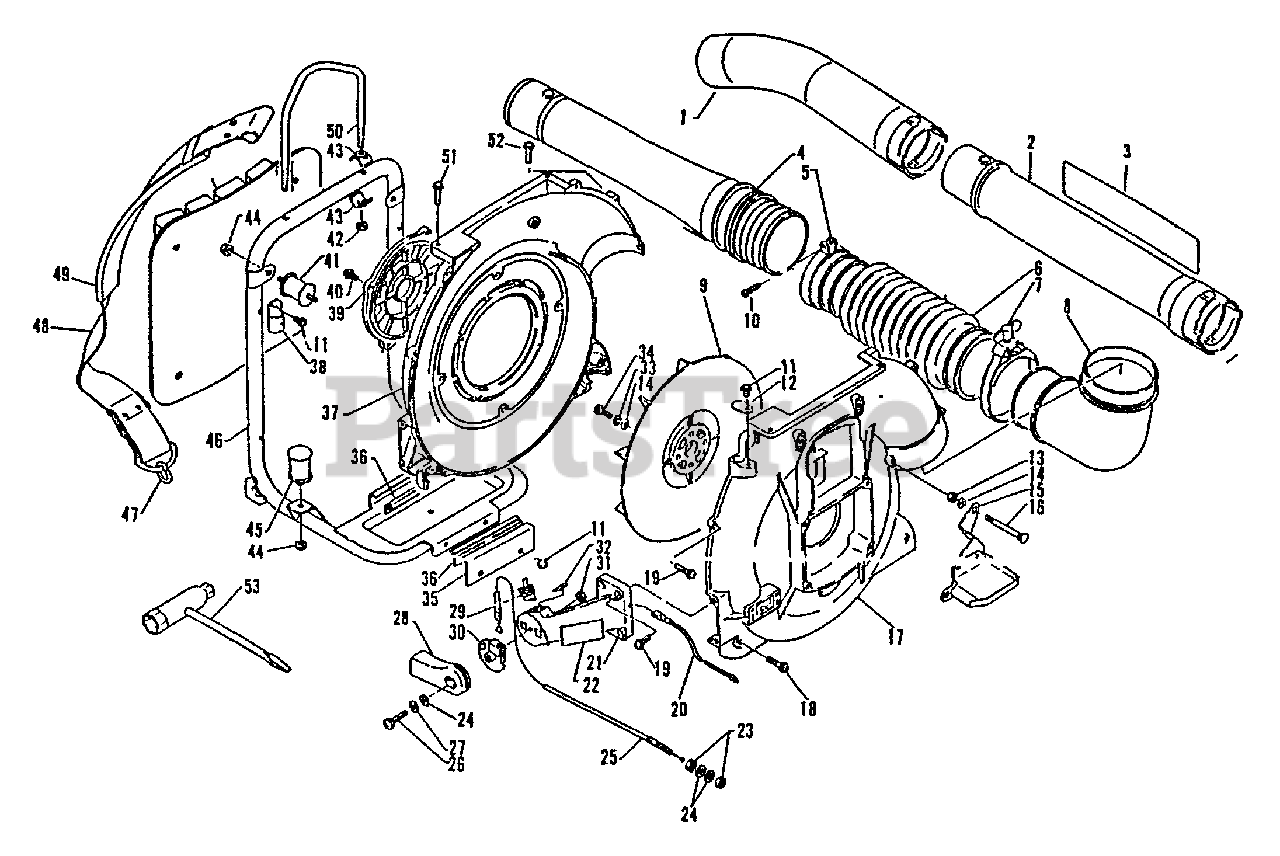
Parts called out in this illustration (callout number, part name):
1	TUBE, BLOWER - CURVED
2	TUBE, BLOWER - STRAIGHT
3	LABEL - LESCO
4	TUBE, BLOWER - SWIVEL
5	CLAMP KIT
6	TUBE, BLOWER - FLEXIBLE
7	CLAMP
8	TUBE, BLOWER - ELBOW
10	SCREW - 5X25
11	SCREW - 5X10
13	NUT - 5
14	WASHER - 5
15	BRACKET, MUFFLER COVER
16	BOLT, ELBOW
17	COVER, FAN - LEFT
18	SCREW - 5X25
19	SCREW - 5X20
21	MOUNT, THROTTLE LEVER
22	LABEL - CAUTION
24	WASHER - 6
25	CABLE, THROTTLE
26	SCREW - 6X25
27	WASHER - 6
28	TRIGGER, THROTTLE
29	IGNITION SWITCH ASSY
31	LOCKNUT - 6
32	LABEL - STOP
33	LOCKWASHER - 5
34	BOLT - 5X16
35	BRACKET, FUEL TANK
36	CUSHION, FUEL TANK
37	COVER, FAN - INNER
38	BRACKET, CUSHION
39	GUARD, DEBRIS
40	BOLT - 6X14
42	LOCKNUT - 6
44	NUT - 6 -- FLANGE
46	FRAME, BACKPACK
47	RING, STRAP
48	BACKPACK STRAP ASSY
49	CUSHION, BACKPACK
51	SCREW - 6X15
52	SCREW - 6X20
53	T-WRENCH - 10X19mm
